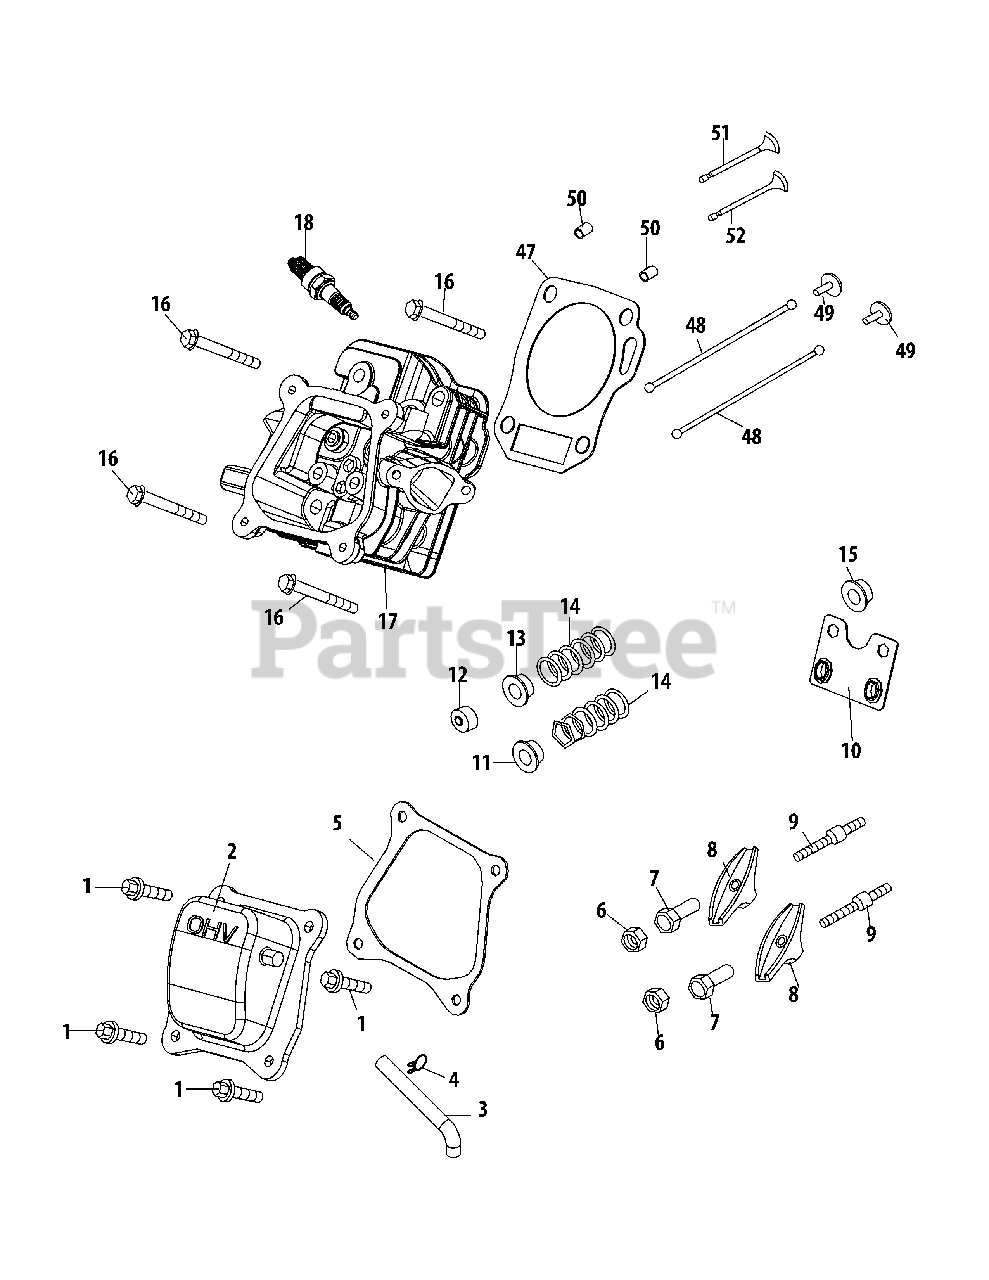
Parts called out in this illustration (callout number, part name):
1	Bolt M6×16
2	Valve Cover
3	Exhaust Piping
4	Breather Hose Clamp
5	Valve Cover Gasket
6	Nut, Pivot Locking
7	Adjusting Nut, Valve
8	Rocker Arm
9	Bolt, Pivot
10	Push Rod Guide
11	Valve Spring Retainer (Intake)
12	Exhaust Lash Cap
13	Valve Spring Retainer (Exhaust)
14	Valve Spring
15	Valve Seal (Intake)
16	Bolt M8×55
17	Cylinder Head
18	Spark Plug/F6Rtc
47	Gasket, Cylinder Head
48	Push Rod
49	Tappet
50	Dowel Pin 10×16
51	Exhaust Valve
52	Intake Valve
